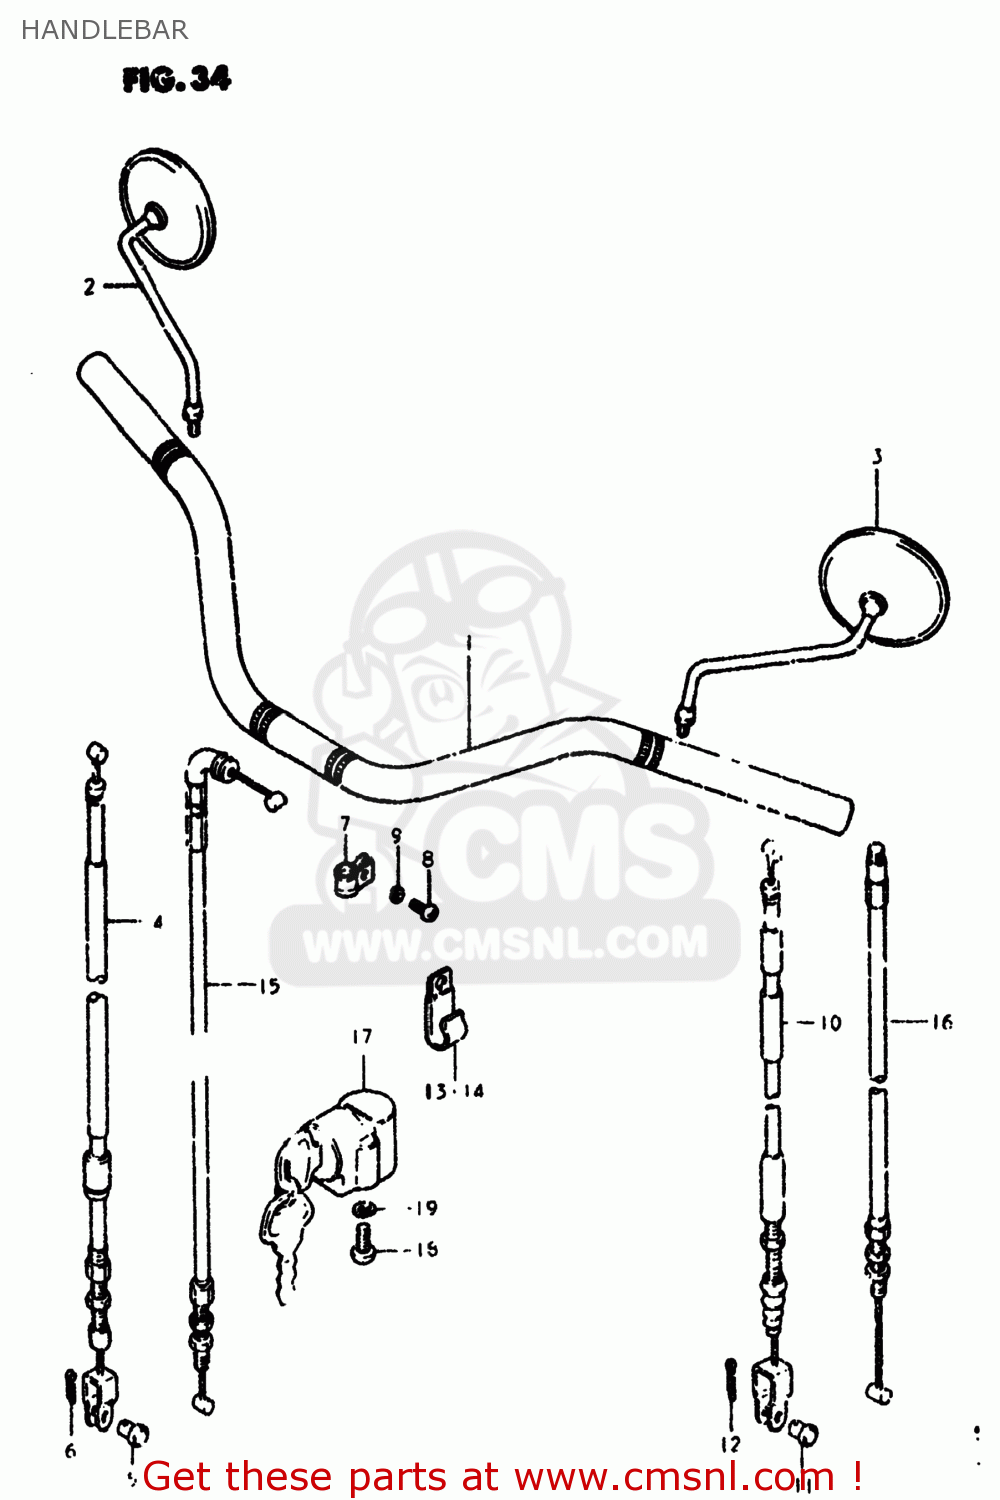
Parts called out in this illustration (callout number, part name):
1	HANDLEBAR
2	MIRROR ASSEMBLY,REAR VIEW
3	MIRROR ASSEMBLY,REAR VIEW
4	CABLE ASSY,FR BRAKE
5	PIN(L:17.5)
6	PIN
7	GUIDE,CABLE
8	SCREW
9	LOCK WASHER
10	CABLE ASSEMBLY,CLUTCH
11	PIN(L:15)
12	PIN
13	CLAMP
14	CLAMP
15	CABLE ASSEMBLY,THROTTLE
16	CABLE ASSEMBLY,DECOMPRESSION
17	LOCK ASSEMBLY,STEERING
18	SCREW
19	LOCK WASHER
